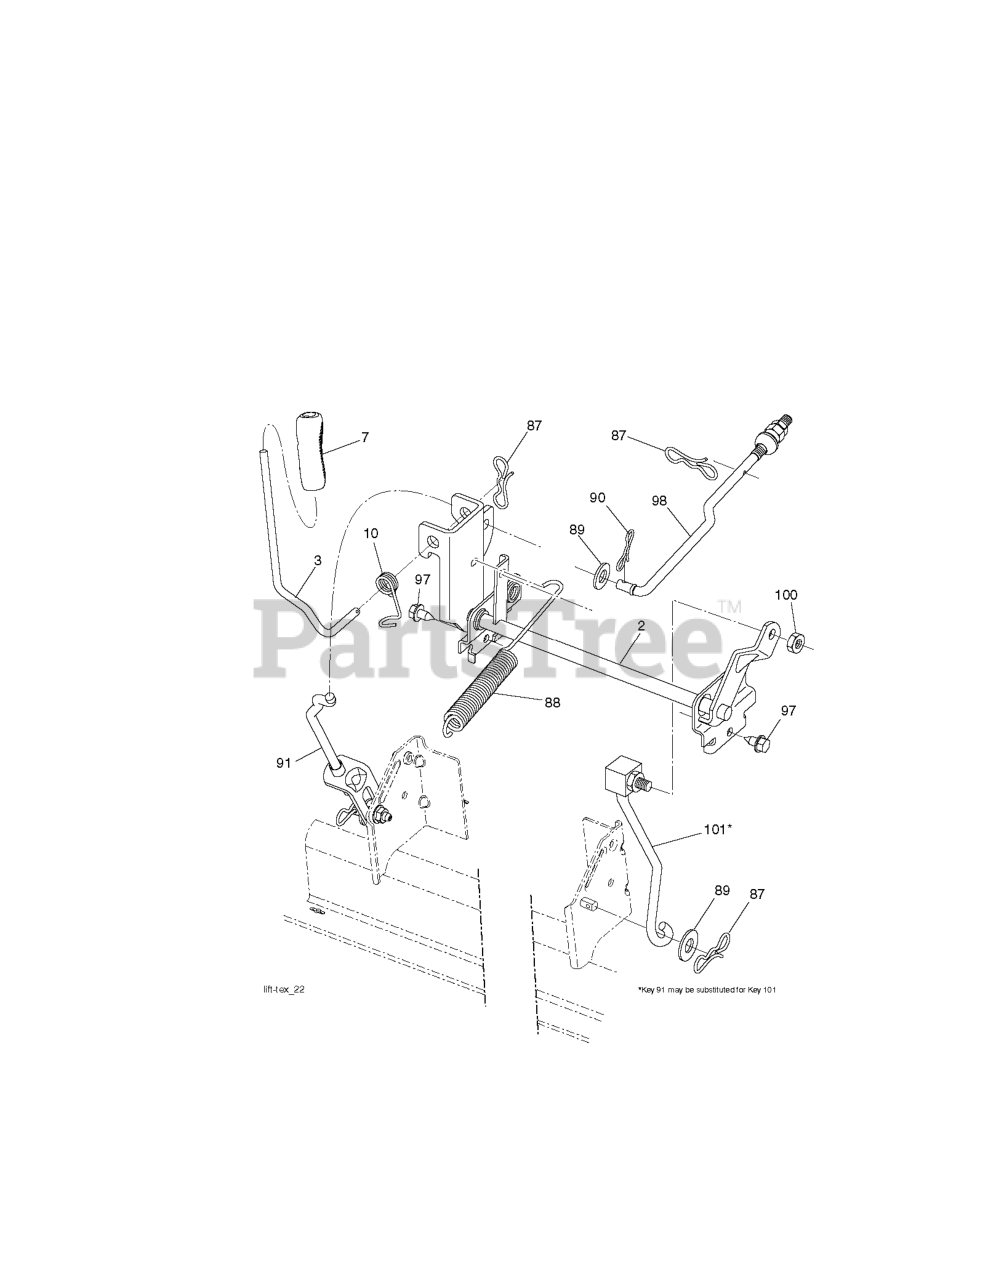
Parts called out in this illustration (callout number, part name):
2	SHAFT.ASM.CROSS.LIFT
3	LEVER.LIFT.HANDLE.LT
7	GRIP.HANDLE.LIFT.PVC.BLACK
10	SPRING.TORSION.LIFT.HANDLE
87	PIN.COTTER.7/16.BOW TI.
88	SPRING.LIFT.ASSIST
89	WASHER.CLEAR.ZINC
90	PIN.COTTER.5/16.BOW TI
91	LINK.ASM.LIFT.REAR
97	SCREW, 3/8-16X3/4
98	LINK.ASM.SUSP.FRONT.MW
100	LOCKNUT
101	LINK.ASM.LIFT.FIXE.38/42/46"
